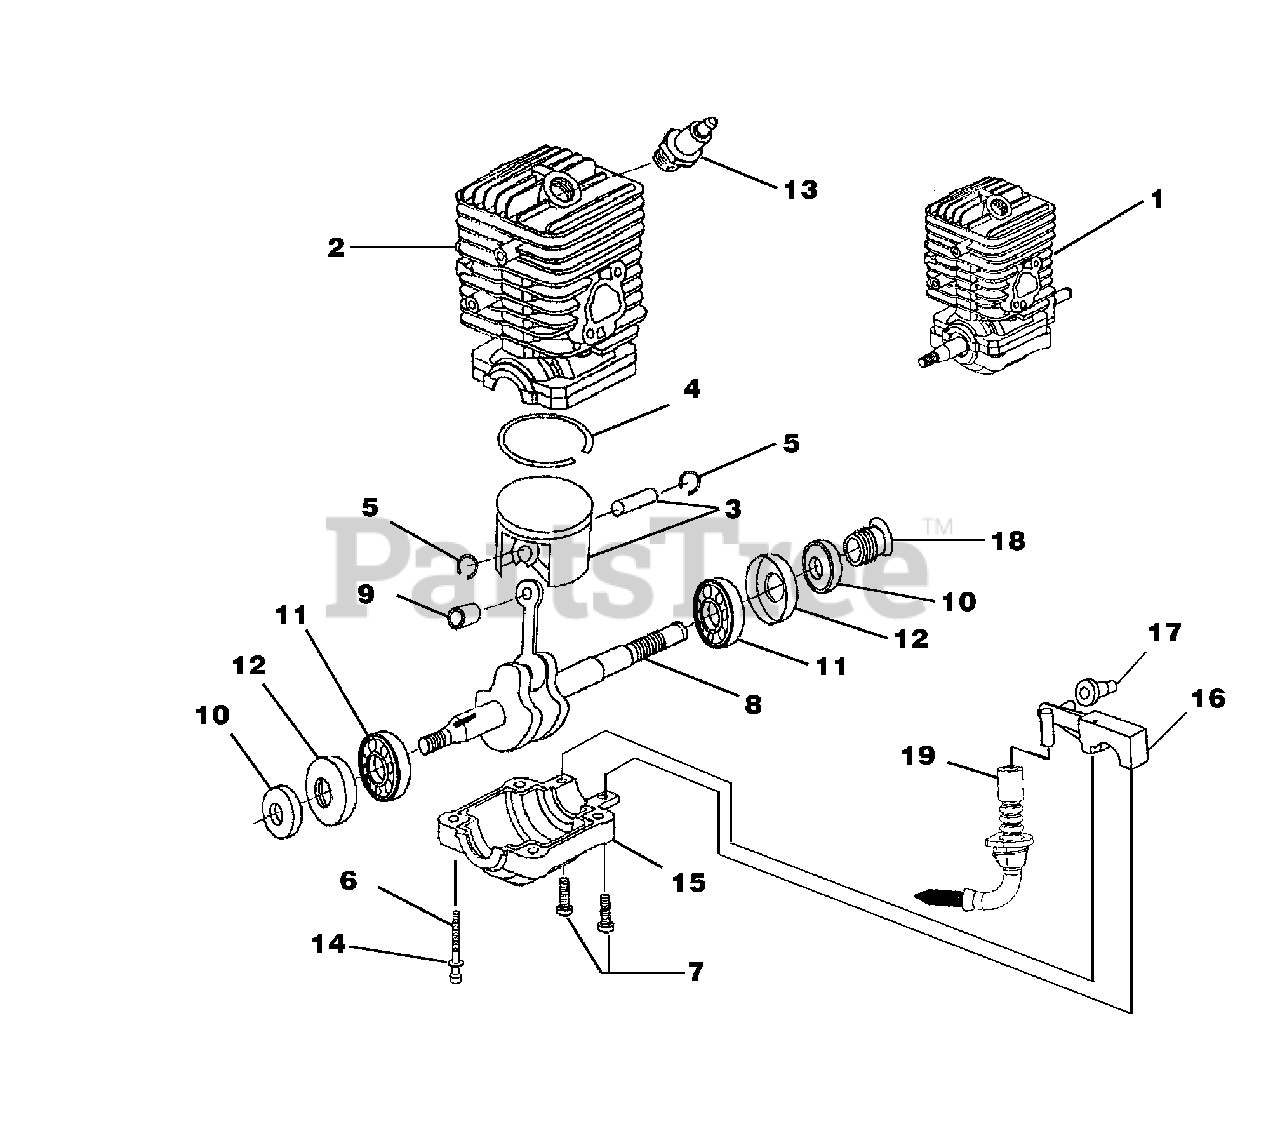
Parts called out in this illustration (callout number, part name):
1	Short Block
2	Cylinder Kit
3	Piston & Pin
4	Piston Ring
5	Ring, Retaining
6	Screw, Cap-Socket Hd. (10-24 x 2")
7	Screw, Pan Hd., Plastite (8-16 x 5/8")
8	Crankshaft & Rod Assy
9	Bearing, Needle
10	Shaft Seal
11	Bearing & Rubber Case
12	Rubber Case
13	Spark Plug
14	Washer
15	Lower Crankcase
16	Oil Pump Kit
17	Grommet, Oil Outlet
18	Left Hand Worm
19	Oil Intake Tube w/Filter
